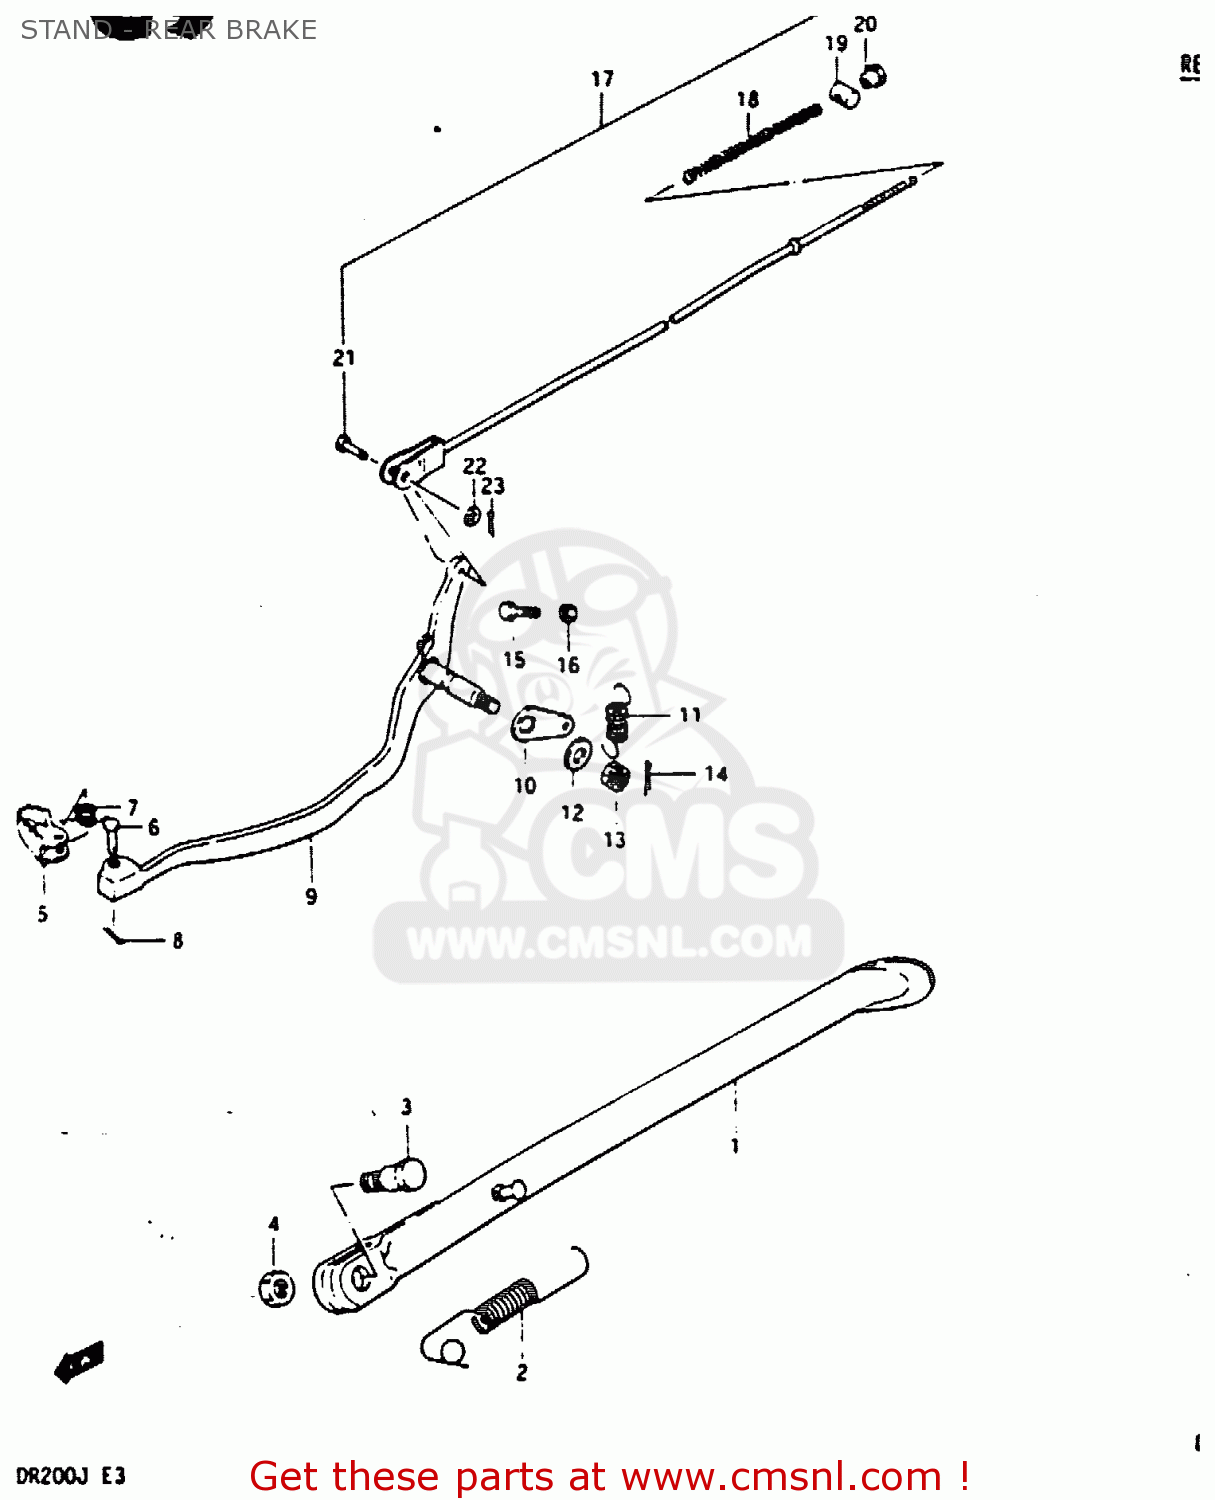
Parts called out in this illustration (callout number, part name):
1	STAND,SIDE
2	SPRING
3	BOLT L:30
4	NUT
5	PEDAL,BRAKE
6	PIN
7	SPRING
8	PIN
9	ARM,BRAKE PEDAL
10	ARM,BRAKE RETURN SPRING
11	SPRING
12	WASHER
13	NUT 8MM
14	PIN 20X20
15	BOLT(6X23)
16	NUT 6MM
17	ROD ASSEMBLY,REAR BRAKE
18	SPRING
19	PIN
20	NUT (6MM)
21	PIN(L:13.5)
22	WASHER
23	PIN 20X20
